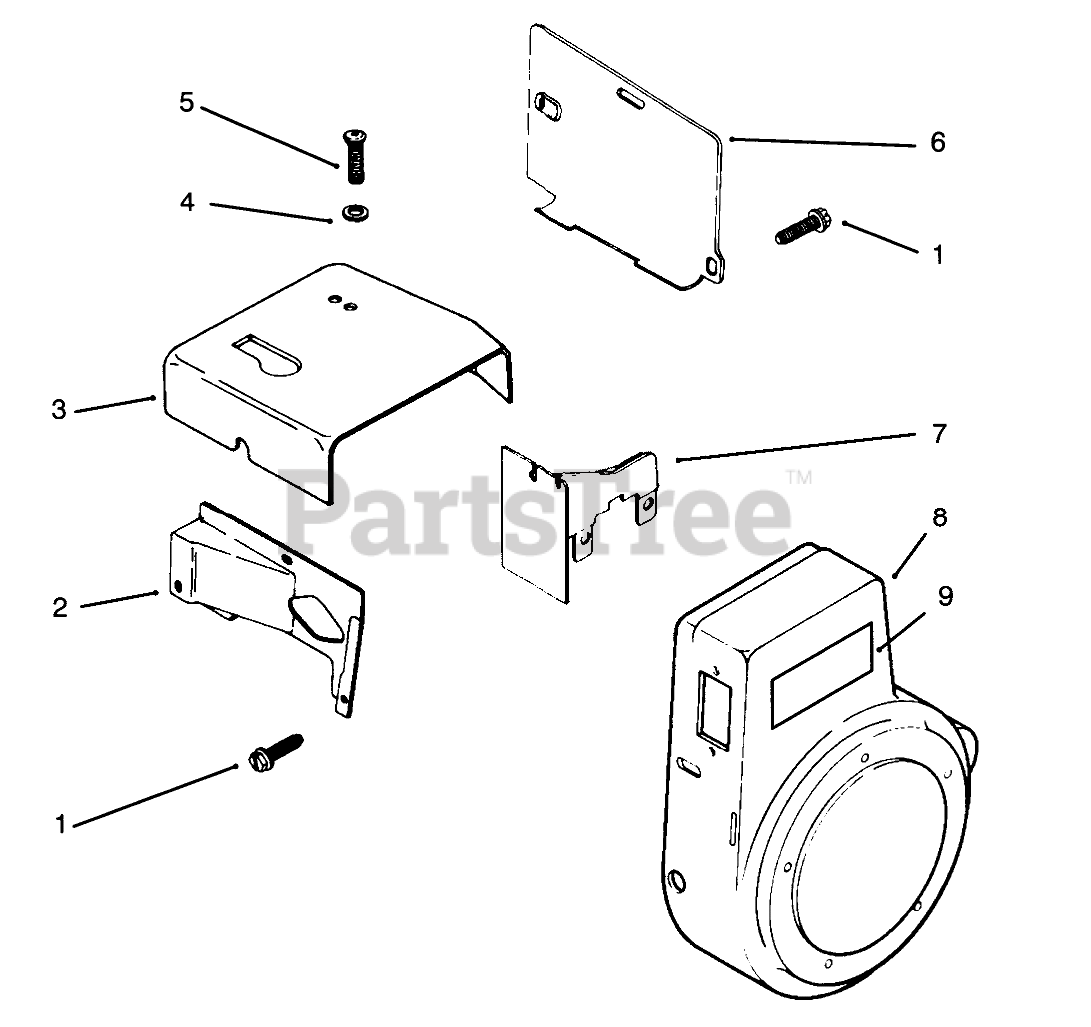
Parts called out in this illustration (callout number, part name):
1	Screw Hex Hd
2	Baffle-SideAir
3	Baffle-Head
4	Washer
5	Screw-Pozidriv T.H.
6	Baffle-Cylinder
7	Baffle-Inner
8	Blower Housing
9	Decal-HP
